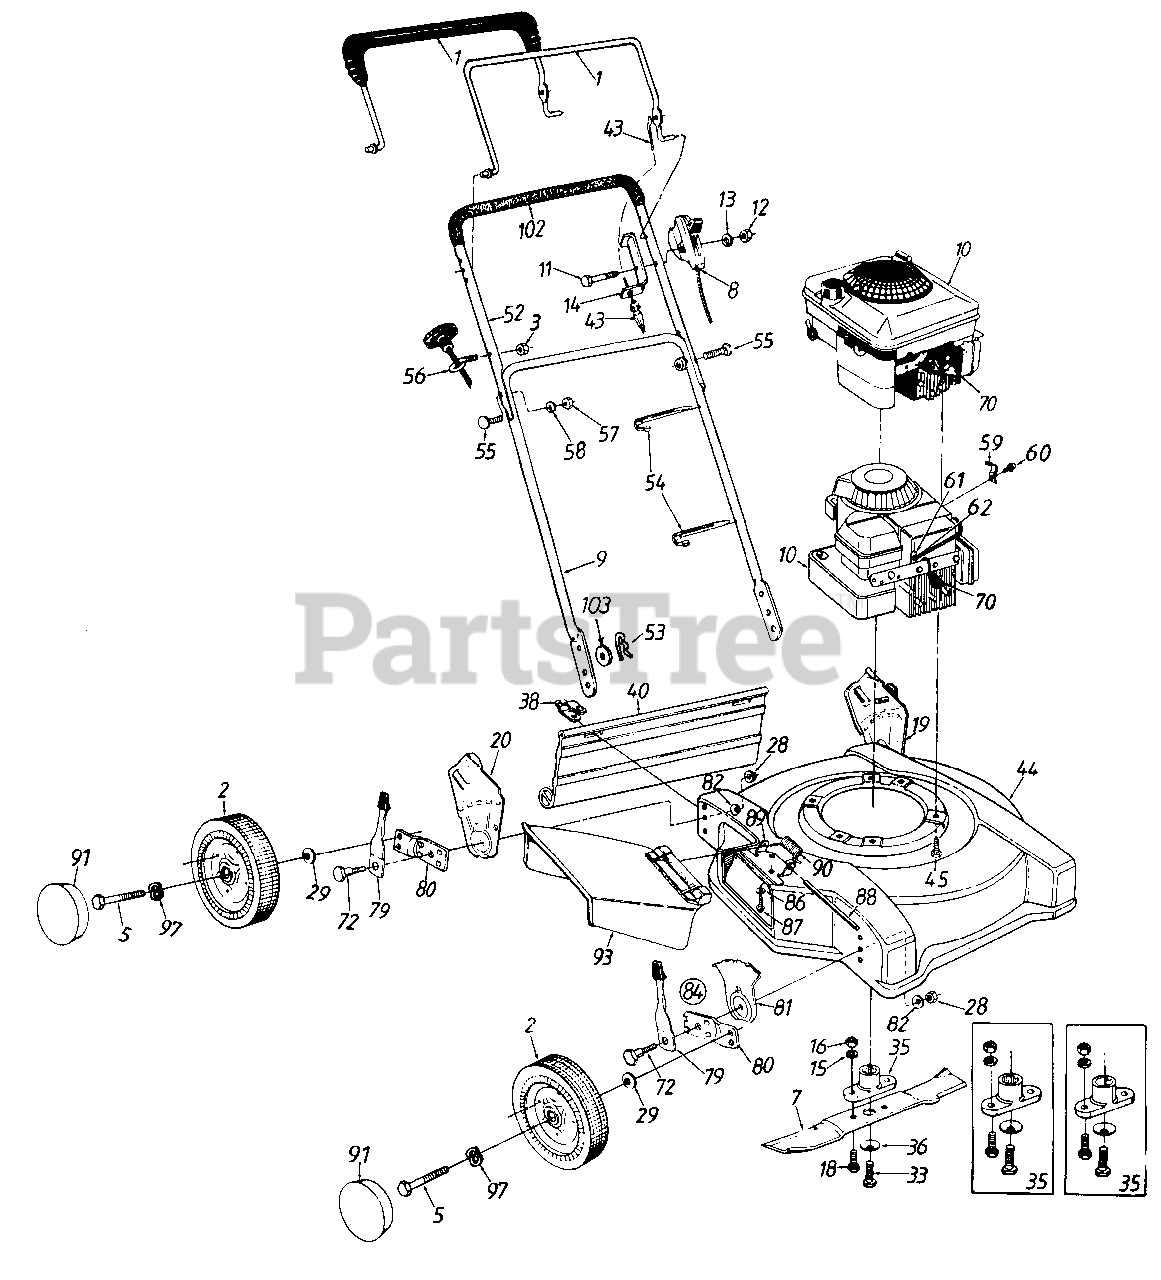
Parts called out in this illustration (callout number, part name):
1	Control Handle Ass'y.
2	Wheel Ass'y. Comp.
3	Hex L-Nut 1/4-20 Thd.
5	Axle Bolt
7	20" Blade
8	Throttle Control Ass'y. Comp.-49.6
9	Lower Handle
10	Engine
11	Hex Bolt 1/4-20 x 1.875" Lg.*
12	Hex Nut 1/4-20 Thd.*
13	Spr. Wash. .265" I.D. x .562"
14	Cable Mtg. Bracket
15	L-Wash. 3/8" I.D.*
16	Hex Nut 3/8-24 Thd.
18	Hex Bolt 3/8-24 x 1.0" Lg.
19	Wheel Brkt. Ass'y.-L.H.
20	Wheel Brkt. Ass'y.-R.H.
28	Hex Nut 3/8-16 Thd.*
29	Bell-Wash. .40" I.D. x .88"
33	Hex Bolt 3/8-24 x 1.5" Lg.
35	Blade Adapter Kit (Keyed)
36	Bell-Wash. .39" I.D.
38	Hinge Clip
40	Rear Flap Ass'y.
43	Control Cable 39"
44	638/N 20" Deck Ass'y.
45	Hex Wash. Hd. TT-Tap Scr. 3/8-16 x 1.00" Lg.
52	Upper Handle
53	Intern. Cot. Pin 5/16" Dia.
54	Cable Tie
55	Curved Carriage Bolt 5/16-18 x 1.38" Lg.
56	Rope Guide
57	Hex Nut 5/16-18 Thd.*
58	L-Wash. 5/16" I.D.*
59	Cable Clamp
60	Hex B-Tap Scr. #10 x .38" Lg.
61	Cable Clamp
62	Hex AB-Tap Scr. #8 x .38" Lg.
70	Spark Plug Boot
72	Shoulder Bolt .50" Dia.
79	Spring Lever Ass'y. w/Knob
81	Height Adj. Plate
82	Bell-Wash. .39" I.D. x 1.38"
86	Bell-Wash. .285" I.D. x .75" O.D.
87	Hex Wash. Hd. Tap Scr. 1/4-20 x .5" Lg.
88	Hinge Pin
89	Adapter Plate
90	Torsion Spring
91	Hub Cap
93	Chute Deflector Ass'y. Comp.
97	Wave Washer 53" I.D.
102	Foam Grip
